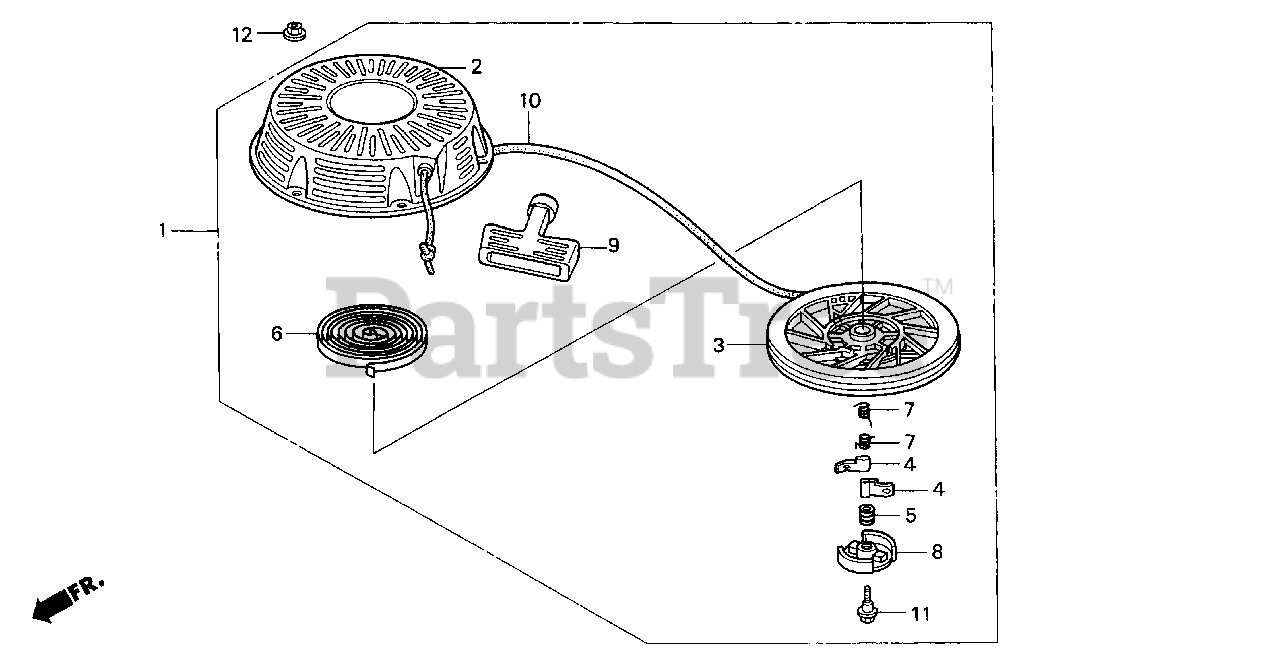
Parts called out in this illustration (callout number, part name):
1	STARTER ASSY., RECOIL *R8* (BRIGHT RED)
1	STARTER ASSY., RECOIL *NH1* (BLACK)
2	CASE, RECOIL STARTER *R8* (BRIGHT RED)
2	CASE, RECOIL STARTER *NH1* (BLACK)
3	PULLEY, RECOIL STARTER
4	RATCHET, STARTER
5	SPRING, FRICTION
6	SPRING, STARTER RETURN
7	SPRING, RATCHET
8	RETAINER, SPRING
9	GRIP, STARTER
10	ROPE, RECOIL STARTER (N/A: USE P/N 08560-ZG921-11)
11	SCREW, CENTER
12	NUT, FLANGE (6MM)
